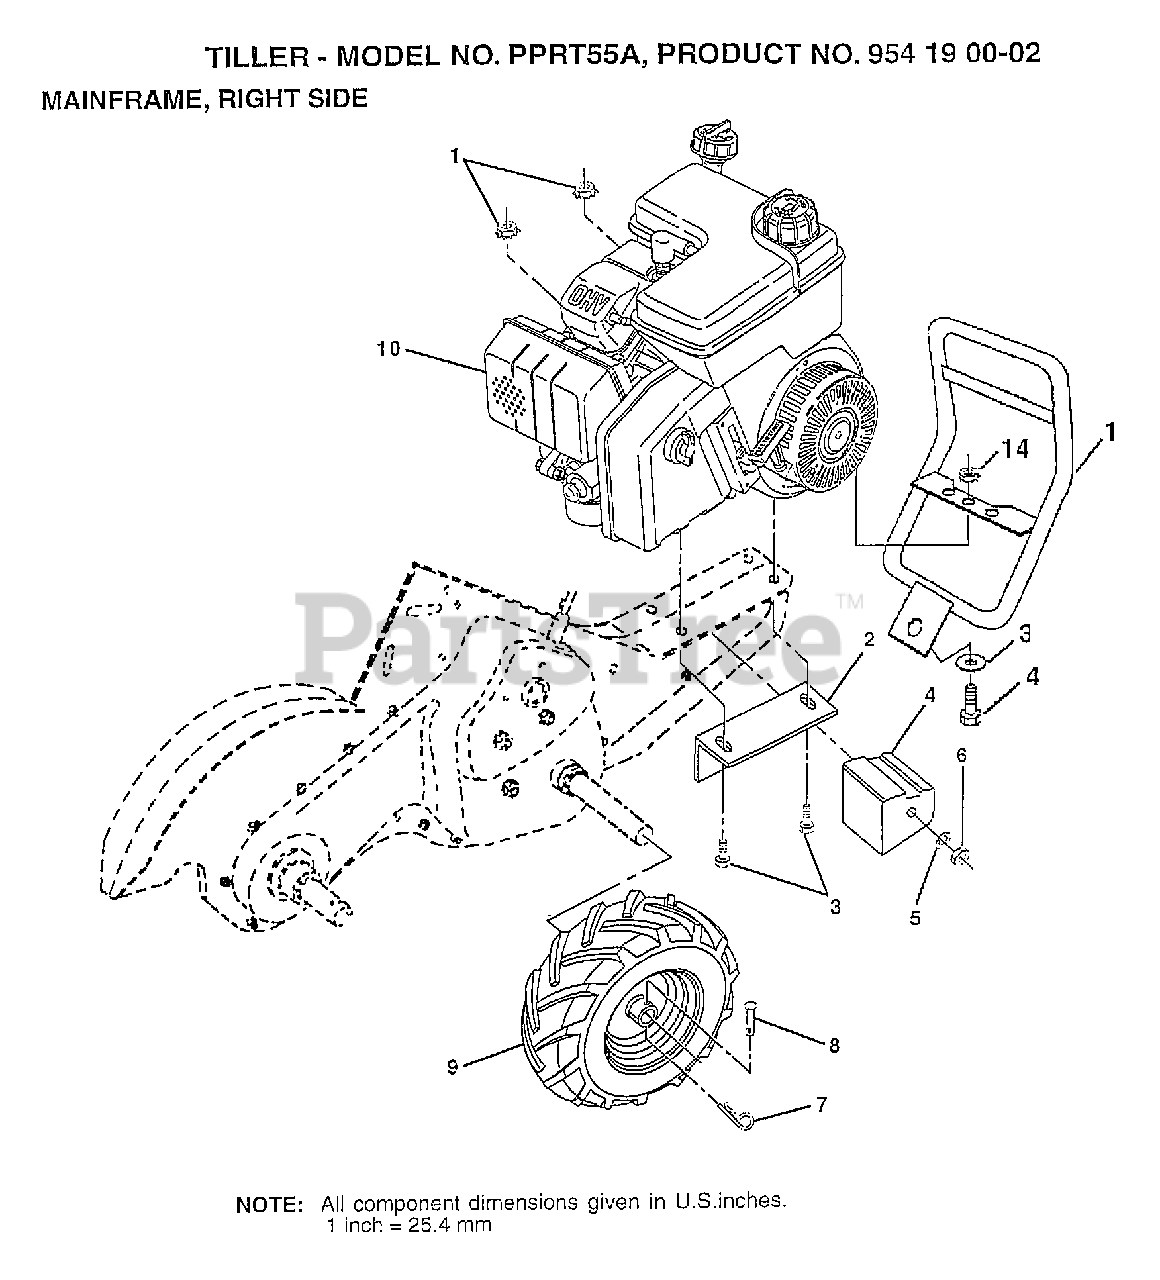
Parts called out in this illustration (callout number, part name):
2	LOCKNUT TI
3	WASHER
4	BOLT
5	BRKT REINFORCEMENT
6	BOLT
7	COUNTER WEIGHT
8	LOCKWASHER
9	NUT.HEX.3/8-16UNC
10	BOLT.HEX.5/16-1.5
12	RIVET DRILLED
13	TIRE TI
